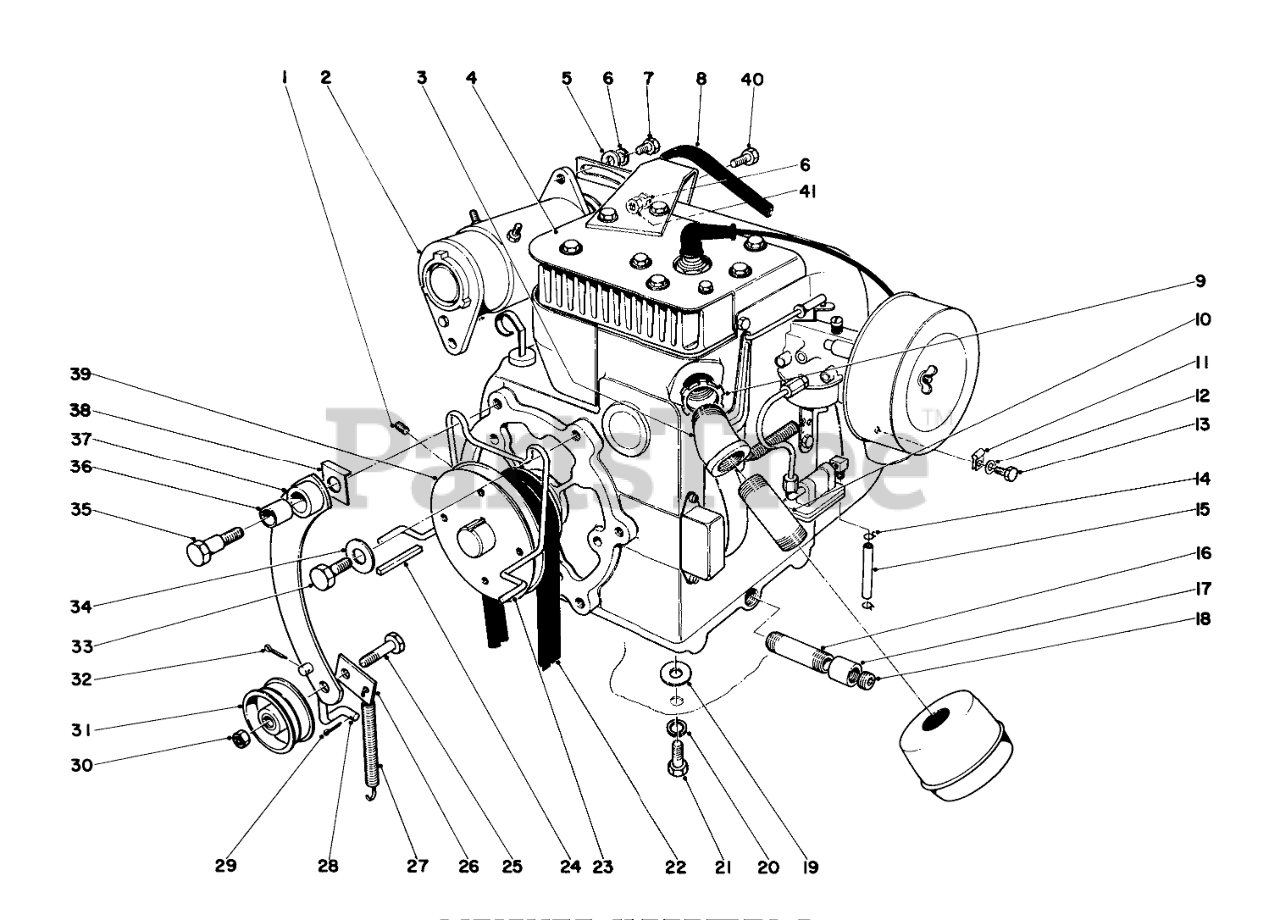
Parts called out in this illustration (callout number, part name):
1	Set Screw
2	Generator
3	Street Elbow
4	Engine 950
5	WASHER-FLAT
6	WASHER-LOCK
7	SCREW-HH
8	Belt, Starter Generator
9	Locknut
10	Pipe Nipple
11	Cable Clamp
12	WASHER-FLAT
13	SCREW-HH
14	Hose Clamp
15	Gas Hose
16	Nipple
17	Coupling
18	Pipe Plug
19	WASHER-FLAT
20	WASHER-LOCK
21	SCREW-HH
22	V-BELT MATCHED SET
23	Belt Guide
24	KEY-SQUARE
25	Leveler Head Bolt
26	Spring Tab
27	Spring
28	Idler Rod
29	PIN-COTTER
30	NUT-HEX
31	Idler Pulley
32	PIN-COTTER
33	SCREW-HH
34	WASHER-FLAT
35	Shoulder Bolt
36	Bushing
37	Idler Arm
38	Clip Belt Guide
39	Pulley Engine
40	SCREW-HH
41	NUT-HEX
